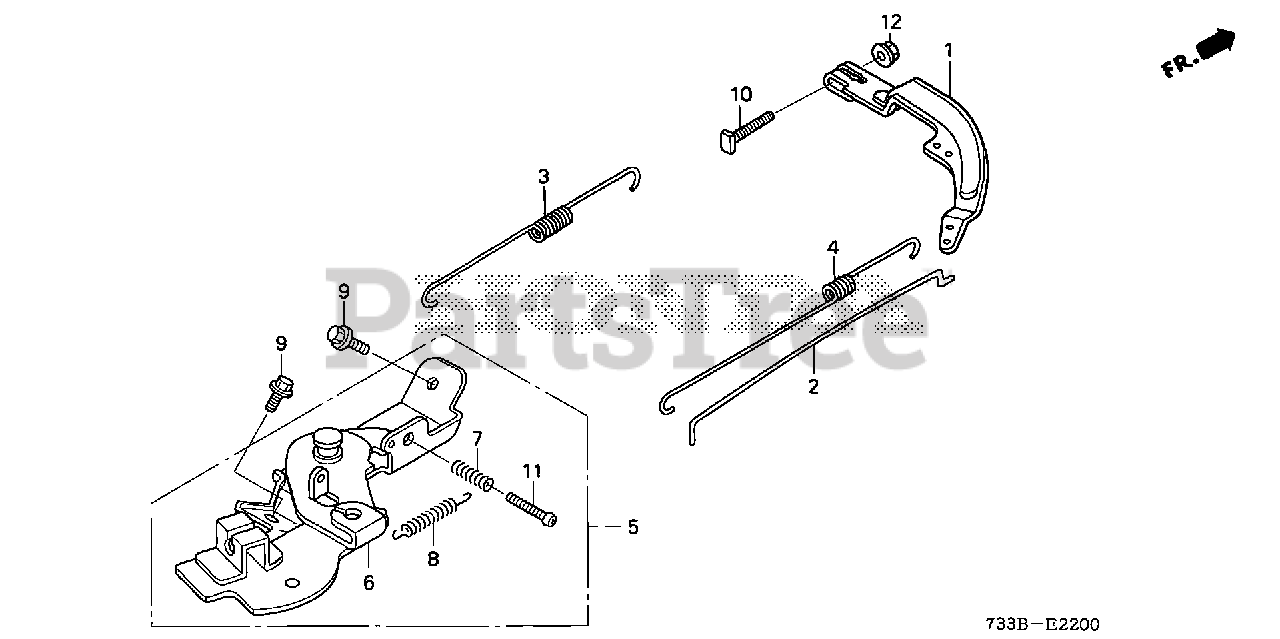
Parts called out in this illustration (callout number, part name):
1	ARM, GOVERNOR
2	ROD, GOVERNOR
3	SPRING, GOVERNOR
4	SPRING, THROTTLE RETURN
5	CONTROL ASSY.
6	LEVER, CONTROL
7	SPRING, CONTROL ADJUSTING
8	SPRING, CABLE RETURN
9	BOLT, FLANGE (6X12) (CT200)
10	BOLT, GOVERNOR ARM
11	SCREW, PAN (5X28)
12	NUT, FLANGE (6MM)
